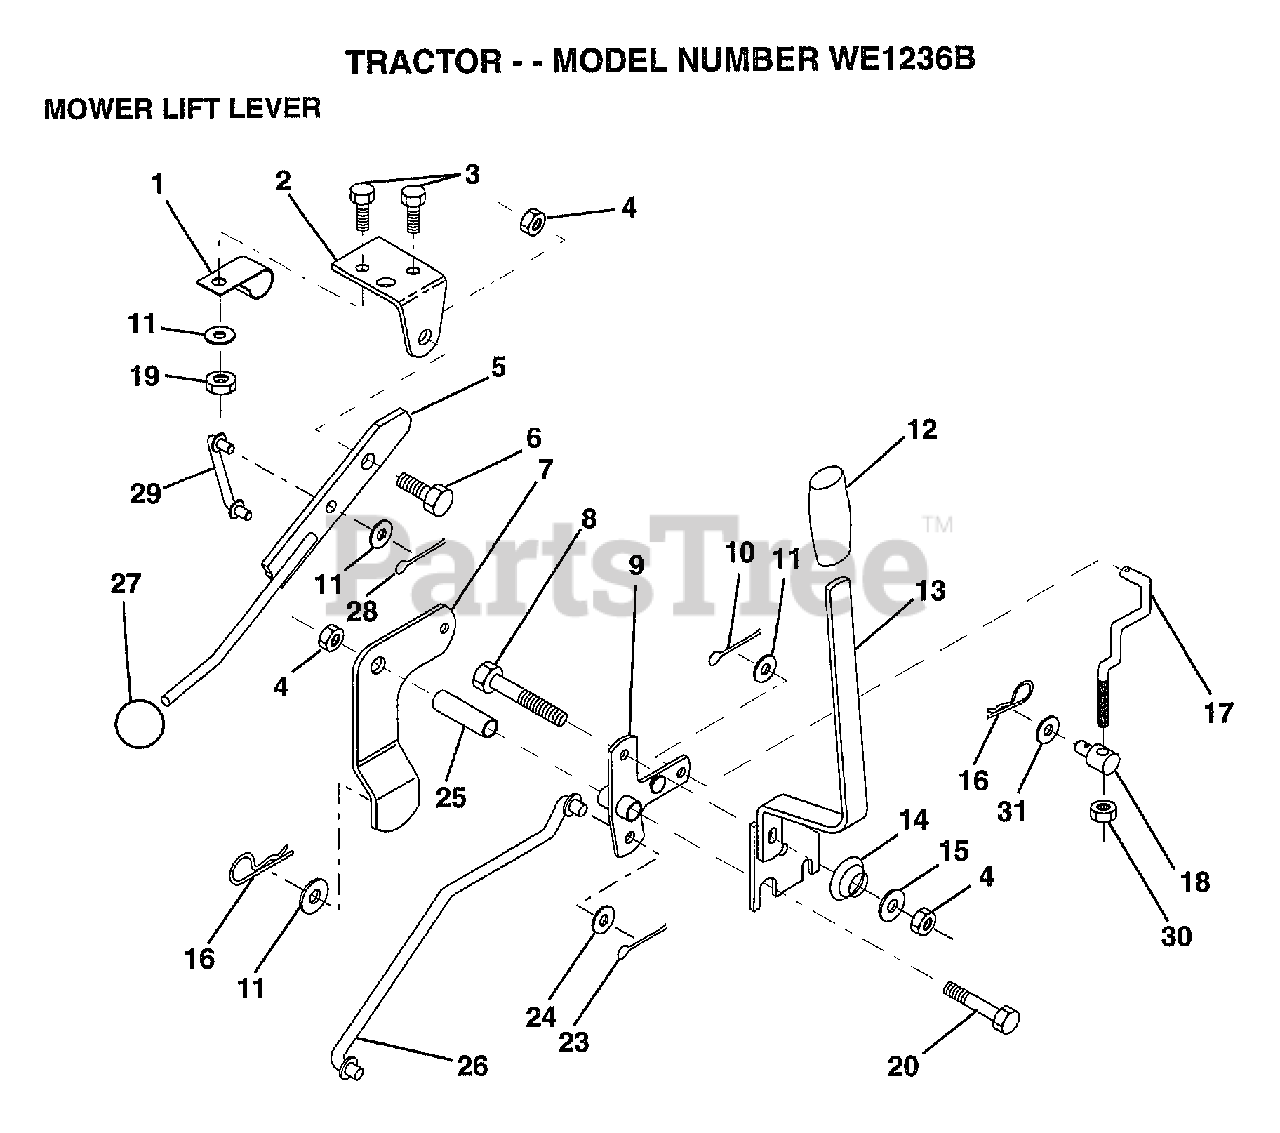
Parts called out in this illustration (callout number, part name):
1	"CLIP,INSULATOR"
2	BRKT CLUTCH
3	BOLT HXHD FIN
5	LEVER.ASM.CLUTCH
6	"BOLT, SHOULDER LT"
7	MWR CLUTCH ARM AS
8	BOLT
9	"BELLCRANK,LIFT"
10	COTTER PIN
11	WASHER
13	HANDLE.ASM.LIFT
14	SPRING COMPRESSIO
15	WASHER T
16	SPRING.RETAINER
17	"LINK,LIFT FRT"
18	TRUNION ADJ
20	BOLT
23	PIN COTTER 1/8
25	TUBE SPACER
26	ROD LIFT MOWER
27	KNOB T(3/8 HOLE)
29	CLUTCH LINK
30	NUT
31	WASHER
